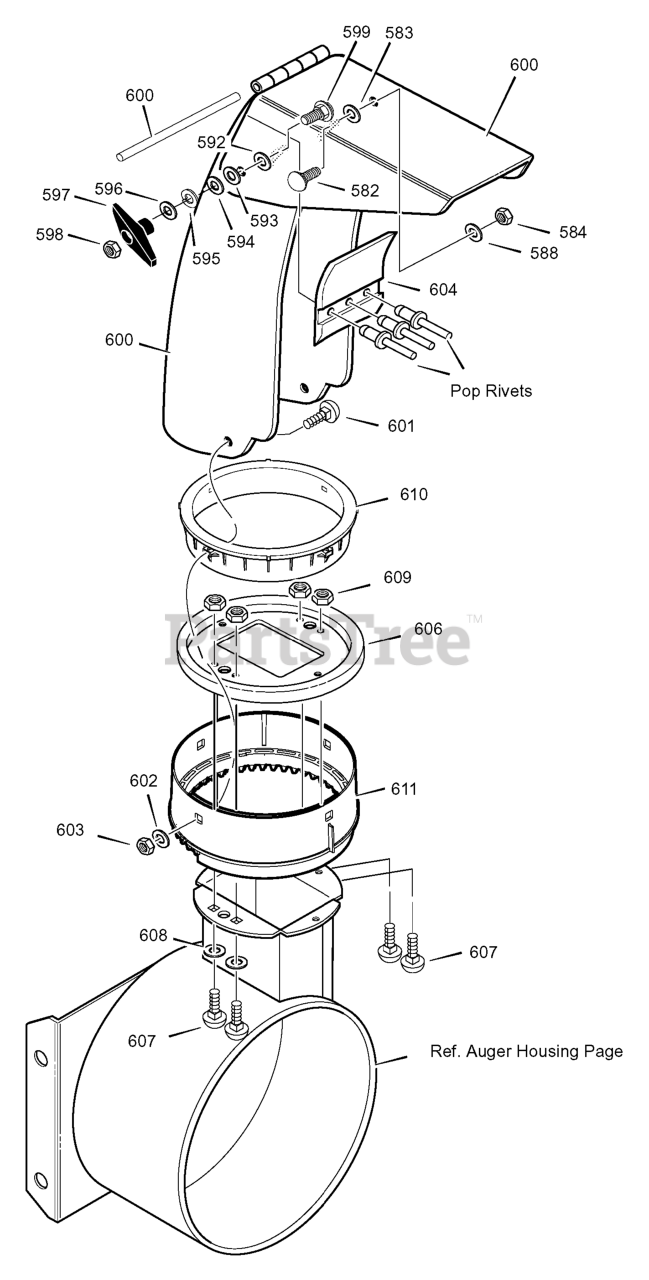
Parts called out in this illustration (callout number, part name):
582	BOLT, CARRIAGE 5/16-18 X.75
583	WASHER, PLASTIC
584	NUT, 5/16-18 REGHEX NYLOCK
588	WASHER, PLASTIC
592	WASHER, PLASTIC
593	WASHER, PLASTIC
594	WASHER, FLAT
595	WASHER, SPLIT
596	WASHER, FLAT
597	KNOB, T 3.00
598	NUT, 5/16-18 REGHEX
599	BOLT, 5/16-18X1.00
600	CHUTE ASSEMBLY
601	BOLT, 5/16-18 X1.00
602	WASHER, FLAT
603	NUT, 5/16-18 HEXNYL
604	FLAP, CHUTE
606	CHUTE COLLAR
607	SCREW, 1/4-20 X 1.00
608	WASHER, FLAT
609	NUT, 1/4-20 HEX NYLOCK
610	RETAINER RING INNER
611	RETAINER RING OUTER
